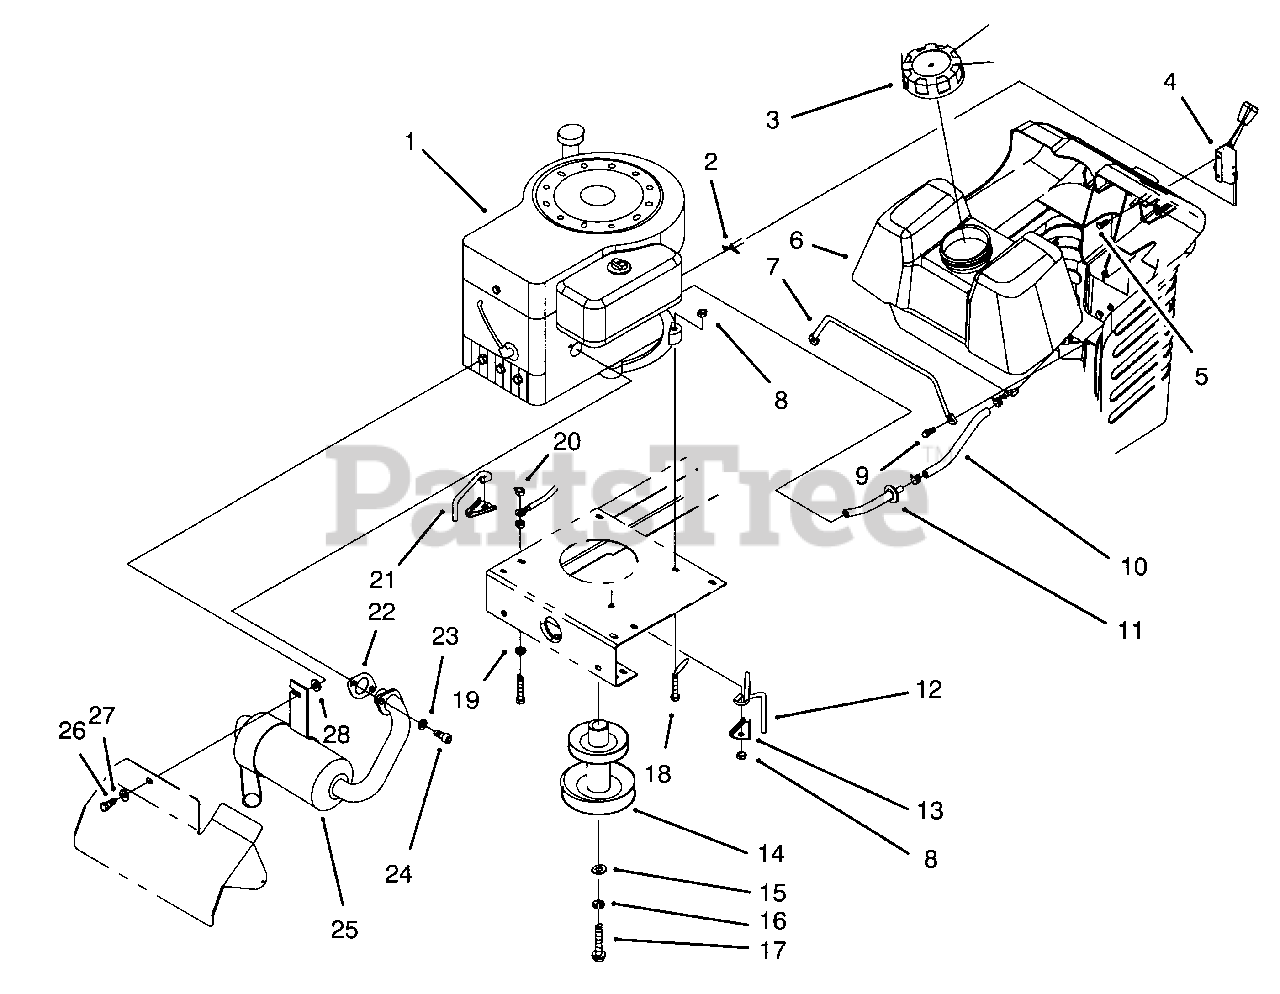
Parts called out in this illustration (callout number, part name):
1	Engine-10 H.P.
2	Cable-Throttle
4	Control-Throttle
5	Screw-Plastite
6	Tank-Gas
7	Rod-Gas Tank
8	Nut-Lock
10	Line-Fuel
11	Clamp-Hose
12	Guide-Belt L.H.
13	Anchor-Belt Guide
14	Pulley-Engine
15	Washer-Flat
16	Washer-Lock
17	Bolt-Blade
18	Screw-Hex Hd. Cap
19	Washer-Ext. Tooth Lock
20	Nut-Keps
21	Guide-Belt R.H.
22	Gasket-Muffler
23	Washer-Lock
24	Screw-Hex Soc. Hd.
26	Screw-Hex Hd. Cap
27	Washer-Lock
